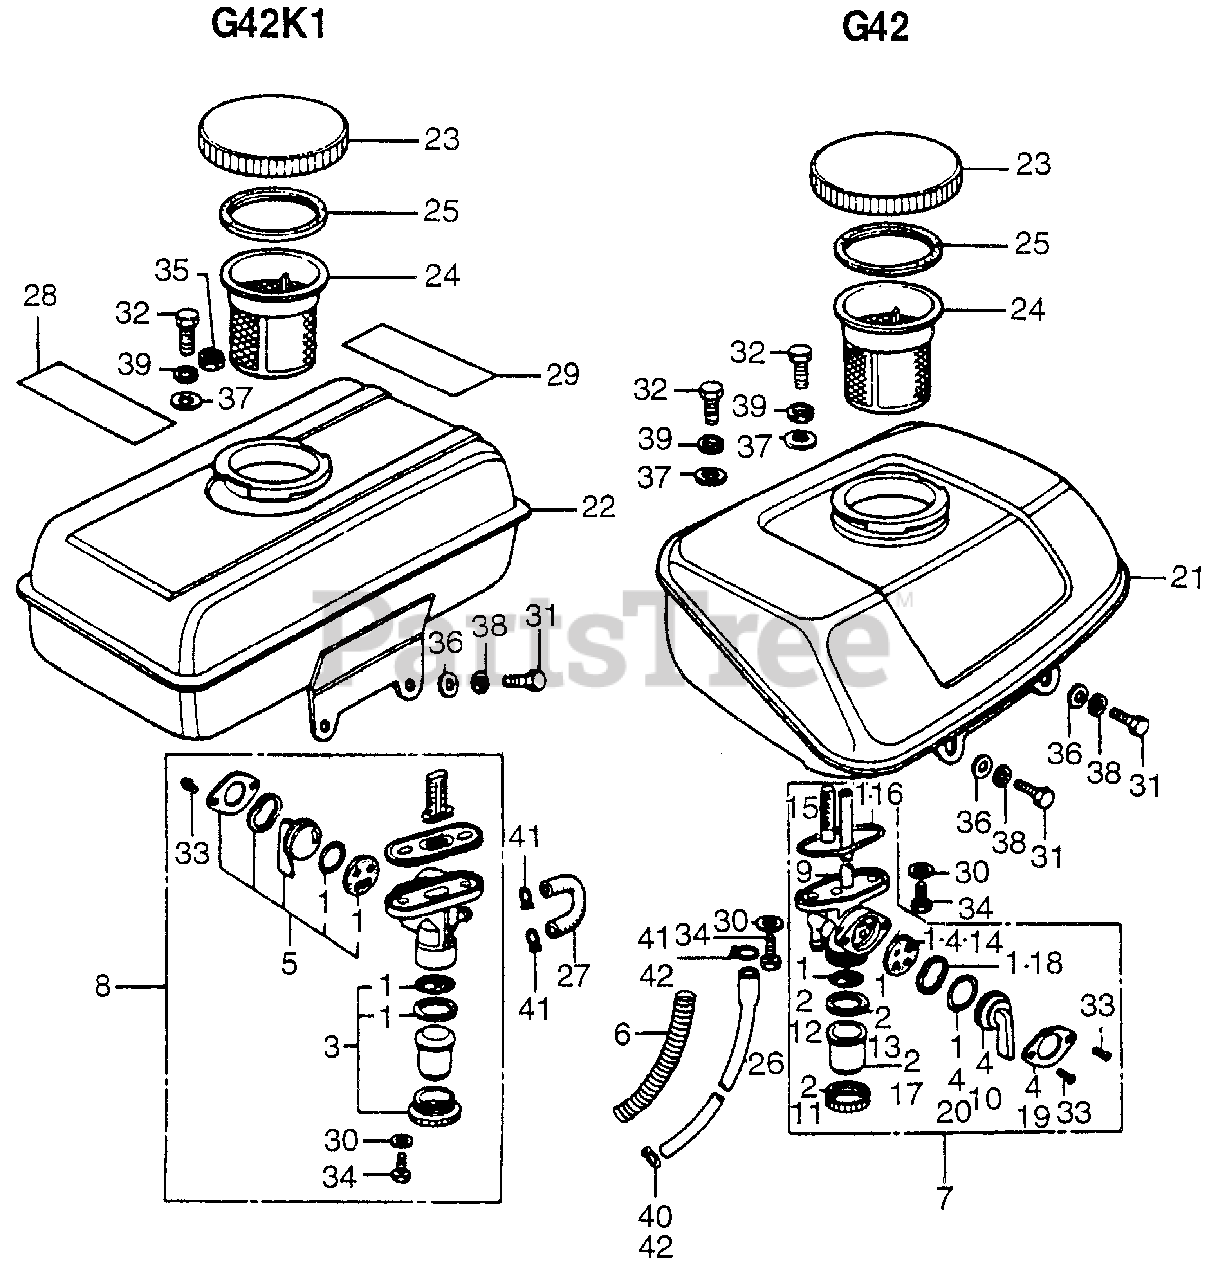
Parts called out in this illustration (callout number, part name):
1	GASKET SET, VALVE
3	CUP SET, STRAINER
5	LEVER SET, VALVE (NOT AVAILABLE)
6	SPRING, FUEL TUBE (NOT AVAILABLE)
8	PETCOCK ASSY.
22	TANK, FUEL *NH31* (MCKINLEY WHITE) (NOT AVAILABLE)
23	CAP, FUEL TANK (NOT AVAILABLE)
24	FILTER, FUEL
25	GASKET, FUEL FILTER (NOT AVAILABLE)
27	TUBE, FUEL (NOT AVAILABLE)
28	MARK A, CAUTION
29	MARK, CAUTION (CO)(ENGLISH/FRENCH)(SPANISH)
30	GASKET, FIBER (6MM)
31	BOLT, HEX. (6X16)
32	BOLT, HEX. (8X20)
33	SCREW, PAN (3X8)
34	SCREW, PAN (6X16)
35	NUT, HEX. (8MM)
36	WASHER, PLAIN (6MM)
37	WASHER, PLAIN (8MM)
38	WASHER, SPRING (6MM)
39	WASHER, SPRING (8MM)
41	CLIP, TUBE (B10)
